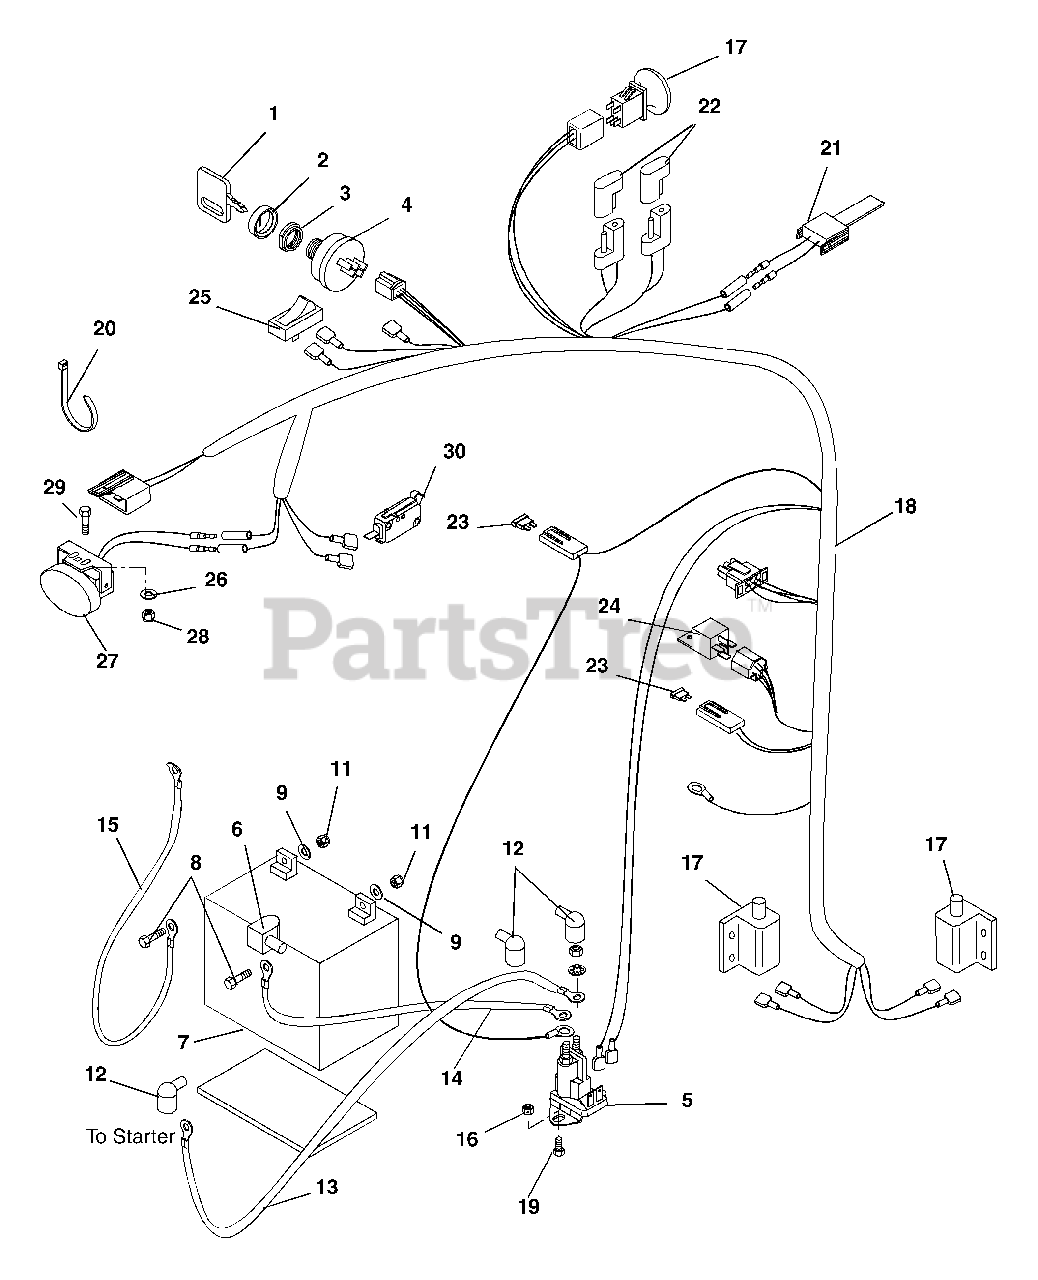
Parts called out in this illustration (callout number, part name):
1	Key with Cap
2	Cap, Ignition Switch
3	Nut, Panel .625-32
4	Key Switch
5	Solenoid
6	Insulator
7	Battery, Filled
8	Bolt, Hex .25-20 x .75 Grade 5
9	Washer, Flat Steel .281 x .62 x .065
10	Washer, Locking .25 x .062 Regular
11	Nut, Hex .25-20
12	Boot, Eyelet Terminal
13	Cable, Positive Battery
14	Starter Cable 13"
15	Starter Cable 16"
16	Nut, Spin Lock Flange .312-18
17	Switch, Clutch With Retainer
18	Harness, Rear Engine Rider
19	Screw, Tapping 10-24 x .375 Hex Washer Head
20	Cable Tie
21	Switch, Seat
22	Molded Diode Plug 1 AMP
23	Fuse, 25 AMP
24	Relay
25	Switch, Light
26	Washer, Flat Steel .38 x .87 x .179
28	Nut, Locking Top Flange .31-18
29	Bolt, Round Head Square Neck .31-18 x 1.00 Grade 5
30	Switch
